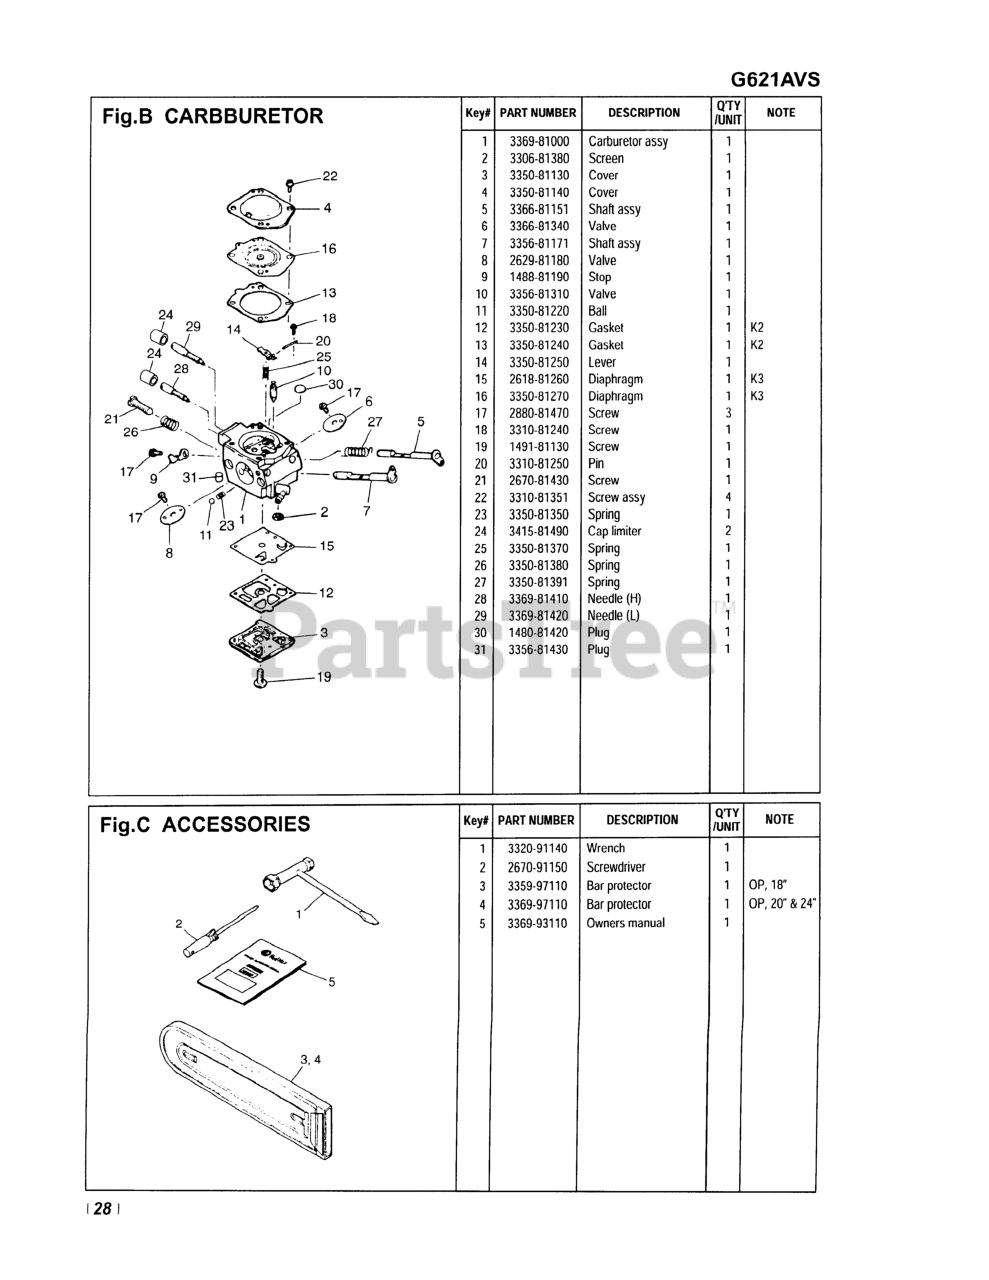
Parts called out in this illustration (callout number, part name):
1	CARBURETOR (HDA-212-1)
4	DIAPHRAGM
6	VALVE, THROTTLE
7	CHOKE SHAFT A
10	VALVE, INLET
11	BALL, FRICTION
12	KIT ONLY
13	KIT ONLY
14	KIT ONLY
15	DIAPHRAGM
16	KIT ONLY
17	SCREW (RPLS 3310-81360)
20	PIN, METERING LEVER
22	SCREW ASSEMBLY
23	SPRING
24	CAP, LIMITER
25	KIT ONLY
26	SPRING, IDLE
27	SPRING, RETURN
28	NEEDLE (H)
29	NEEDLE (L)
30	PLUG, WELSH
31	PLUG, FRICTION
A1	WRENCH, PLUG
A2	SCREWDRIVER
A4	PROTECTOR (USE 3665-97110)
